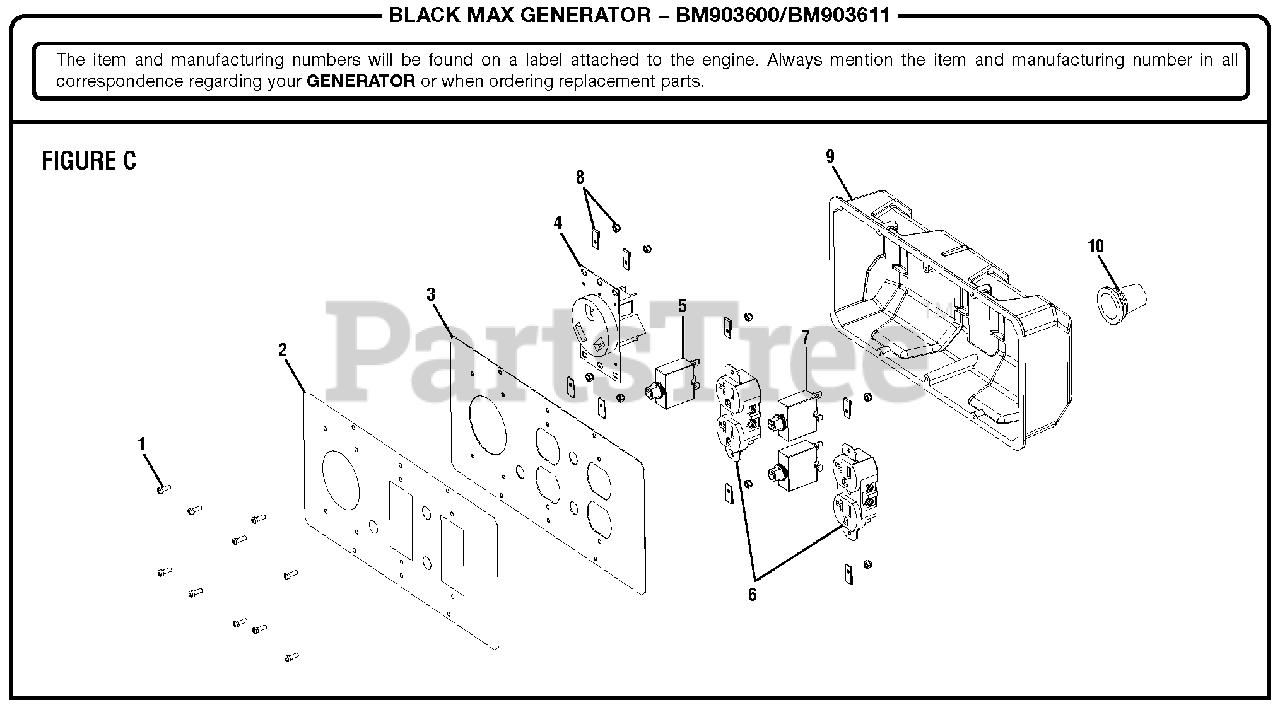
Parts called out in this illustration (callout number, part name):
1	Screw (#6-20 x .38 in., Type B)
2	Label, Electrical Panel 3600
3	Electrical Panel Faceplate
4	Recepticle 120V 30A Rv
5	Circuit Breaker 30 Amp 1 Pole
6	120 Volt Duplex Receptacle (BM903600)
7	Circuit Breaker 20 Amp 1 Pole
8	Nut, Hex #6-32 Nyloc
9	Control Box Housing
10	Wiring Rubber Boot
